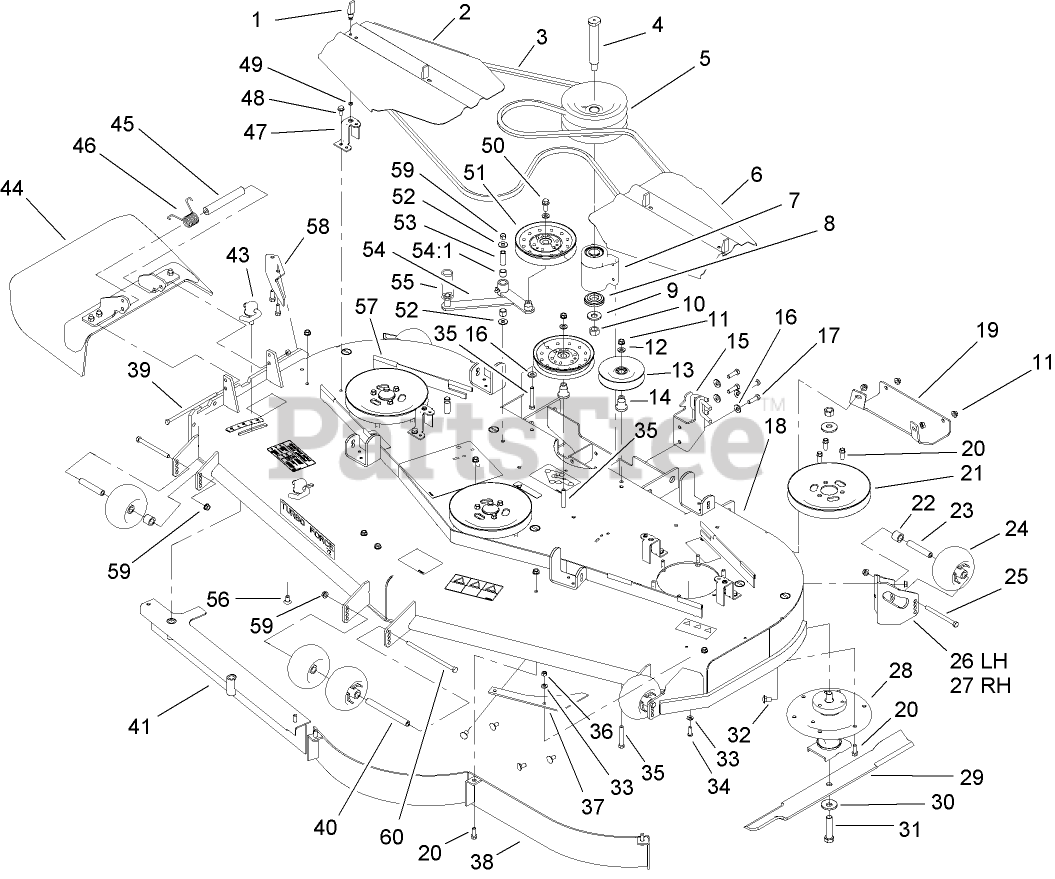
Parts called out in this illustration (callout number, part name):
1	LATCH-SWELL
2	COVER-BELT
3	BELT-V
4	JACKSHAFT
5	SHEAVE-JACKSHAFT
6	COVER-BELT
7	JACKSHAFT ASM
8	SPACER-GUARD, BOTTOM
9	WASHER-SPRING
10	NUT-HEX
11	NUT-HHF, WHIZ
12	WASHER-FLAT
13	PULLEY-IDLER
14	MOUNT-PULLEY
15	GUARD-JACKSHAFT
16	WASHER-BELLEVILLE
17	SCREW-HH
18	DECK ASM
19	Plate-Skid
20	SCREW-HWH
21	Pulley
22	TUBE-SPACER
23	TUBE-SPANNER
24	ROLLER-SCALP, ANTI
25	SCREW-HH
26	MOUNT-WHEEL, LH
27	MOUNT-WHEEL, RH
28	SPINDLE ASM
29	BLADE-MID FLOW, 24.5IN
30	Washer-Blade Bolt, Heavy
31	Screw-Cap
32	SCREW-CARR
33	WASHER-SPRING
34	SCREW-HSBH
35	SCREW-HH
36	NUT-LOCK, NI
37	PLATE-TURBO
39	SCREW-HH
40	SPACER-WHEEL
43	LEVER ASM
44	RUBBER DEFLECTOR ASM
45	SPACER
46	SPRING-TORSION
47	BRACKET-COVER
48	SCREW-HWHTF
49	WASHER
50	SCREW-HHF
51	Idler-Flat
52	WASHER-FLAT
53	BUSHING
54	IDLER ARM ASM
54:1	SLEEVE-BEARING
55	SPRING-EXTENSION
56	SCREW-CARR
57	STRIP-SEAL
58	BAFFLE-DISCHARGE
59	NUT-LOCK, NI
60	SCREW-HH
